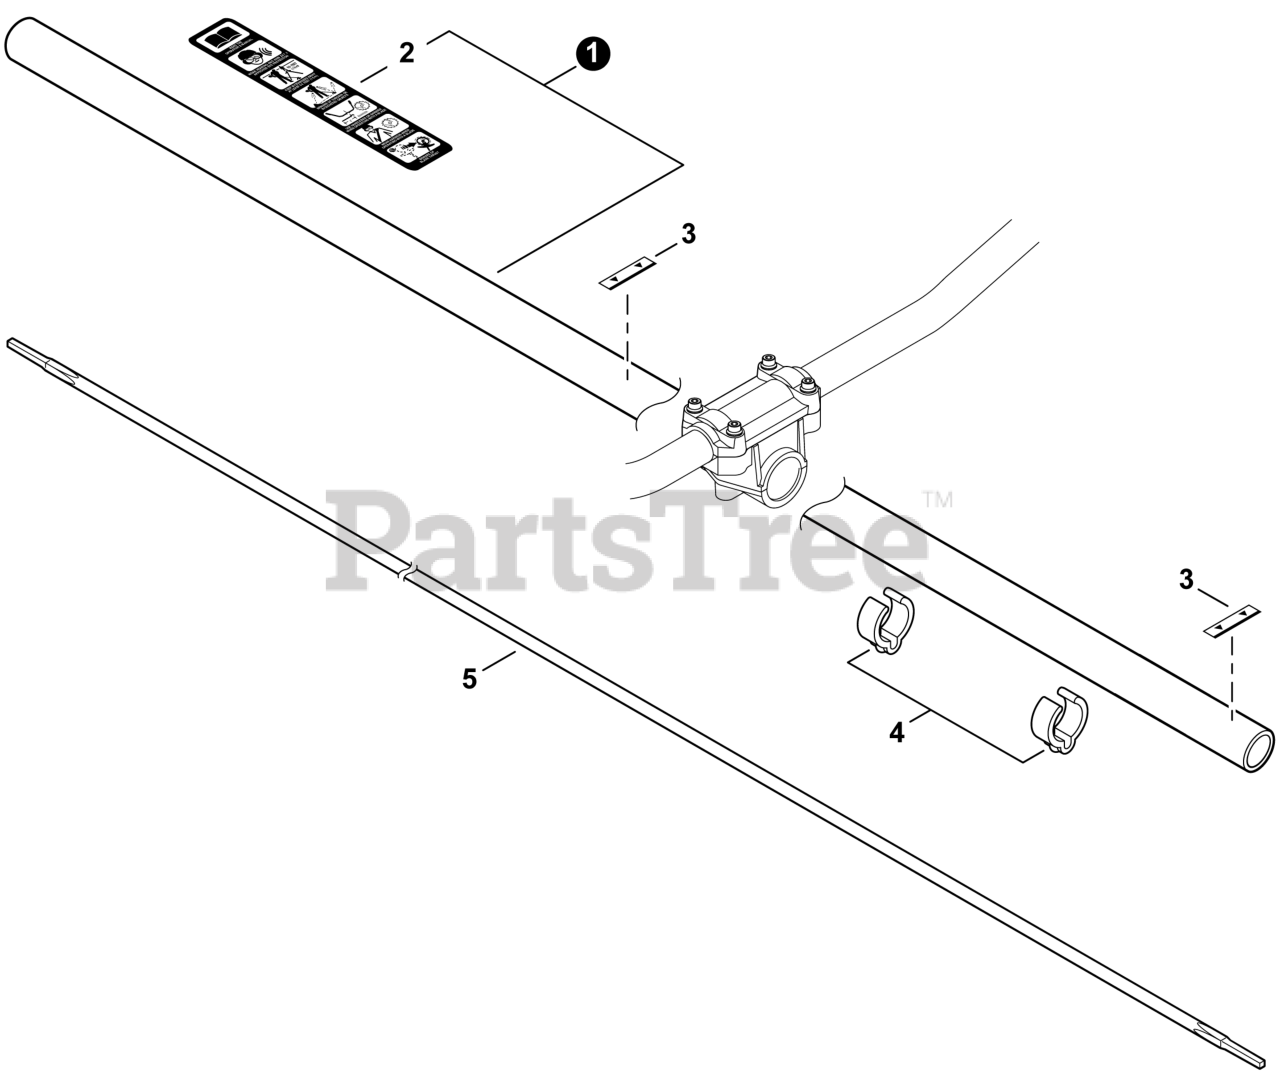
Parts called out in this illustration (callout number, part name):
1	MAIN PIPE ASSY
2	LABEL - CAUTION (BLADE CAPABLE)
3	LABEL - ALIGNMENT
4	CLIP, CABLE 25 MM
5	DRIVESHAFT
